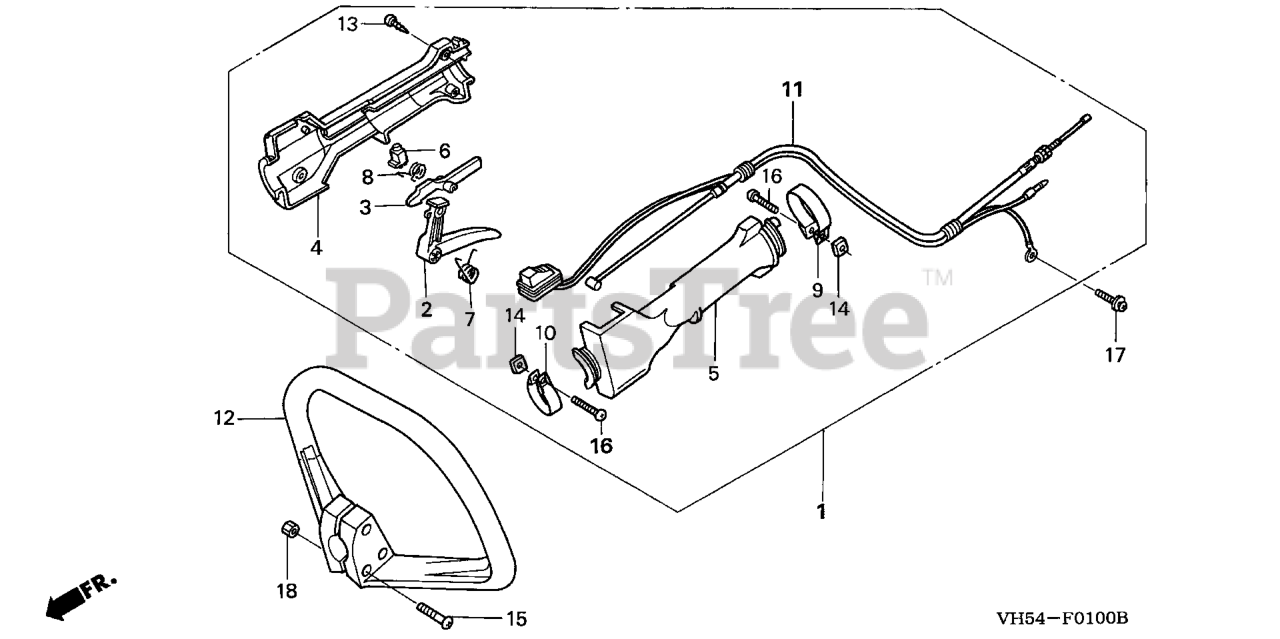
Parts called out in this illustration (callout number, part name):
1	LEVER ASSY., THROTTLE
2	LEVER, THROTTLE
3	LEVER, THROTTLE LOCK
4	GRIP, R. THROTTLE LEVER
5	GRIP, L. THROTTLE LEVER
6	BUTTON, THROTTLE LOCK
7	SPRING, THROTTLE LEVER
8	SPRING, THROTTLE LOCK LEVER
9	BRACKET, THROTTLE LEVER
10	BRACKET, THROTTLE LEVER
11	WIRE HARNESS ASSY.
12	HANDLE, LOOP
13	SCREW, TAPPING (4X18)
14	NUT, SQUARE (6MM)
15	SCREW, PAN (5X28)
16	SCREW, PAN (6X20)
17	SCREW-WASHER (5X12)
18	NUT, HEX. (5MM)
